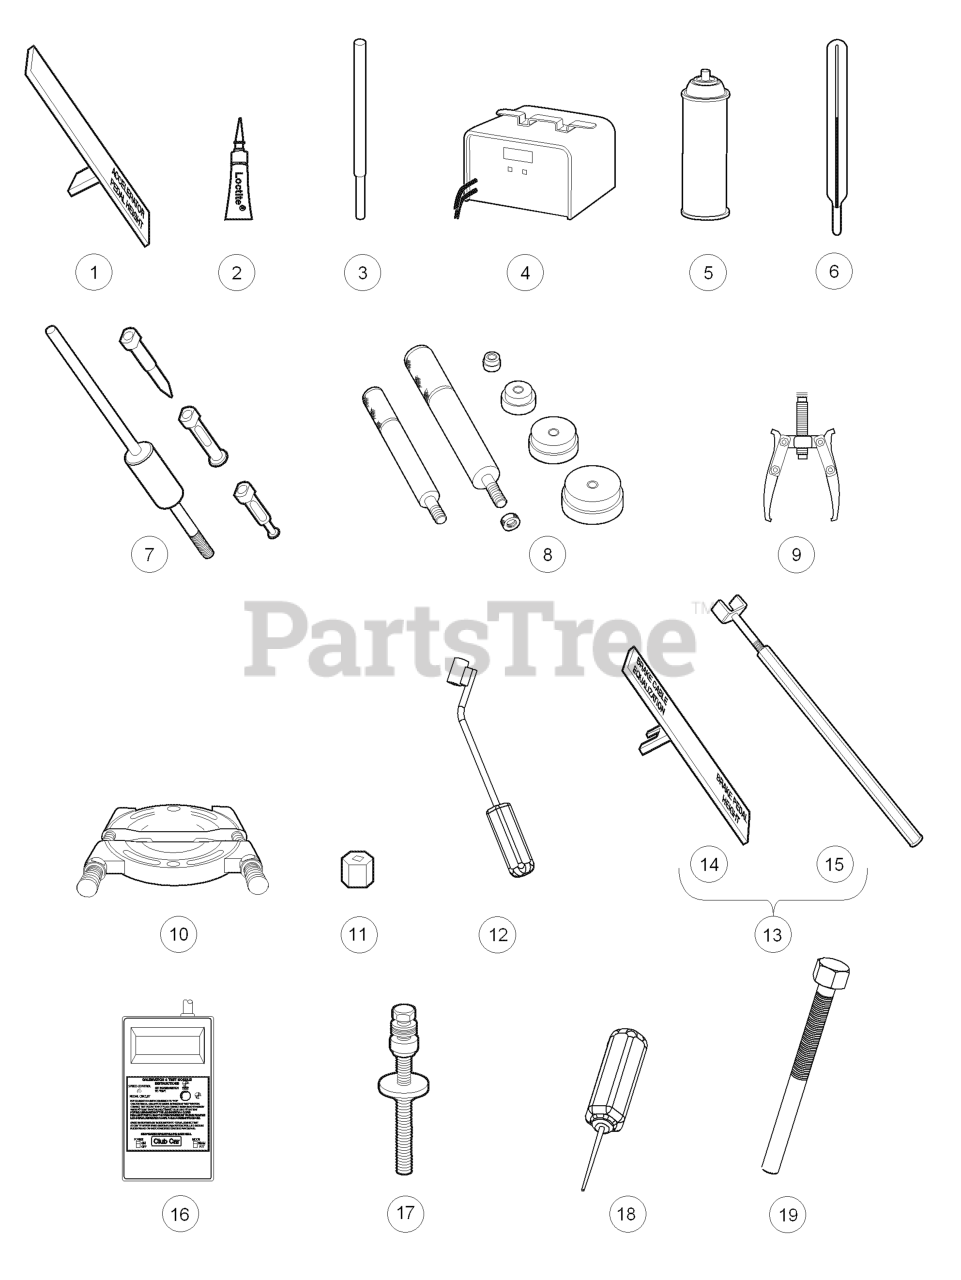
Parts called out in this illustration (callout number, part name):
1	TOOL, ACCEL. PEDAL ADJUSTMENT
2	GUIDE RING ADHESIVE 3 GRAMS
4	BATTERY DISCHARGE UNIT 36/48V
5	BATTERY TERMINAL PROTECT SPRAY
6	BATTERY THERMOMETER
7	BEAR & OIL SEAL REMOVER ASM
8	BEARING DRIVER SET
9	BEARING PULLER
10	BEARING PULLER WEDGE ATTACH.
11	BRAKE ADJUSMENT SOCKET TOOL
12	BRAKE CABLE RELEASE TOOL
13	Brake Pedal Adjustment Tool Kit
14	Brake Pedal Adjustment Tool
15	Brake Pedal Tension Tool
16	CALIBRATION & TEST MODULE
17	CAM INSTALLATION TOOL
18	CHARGER BEZEL TOOL
19	TOOL, REMOVAL, CLUTCH, GAS/DSL
